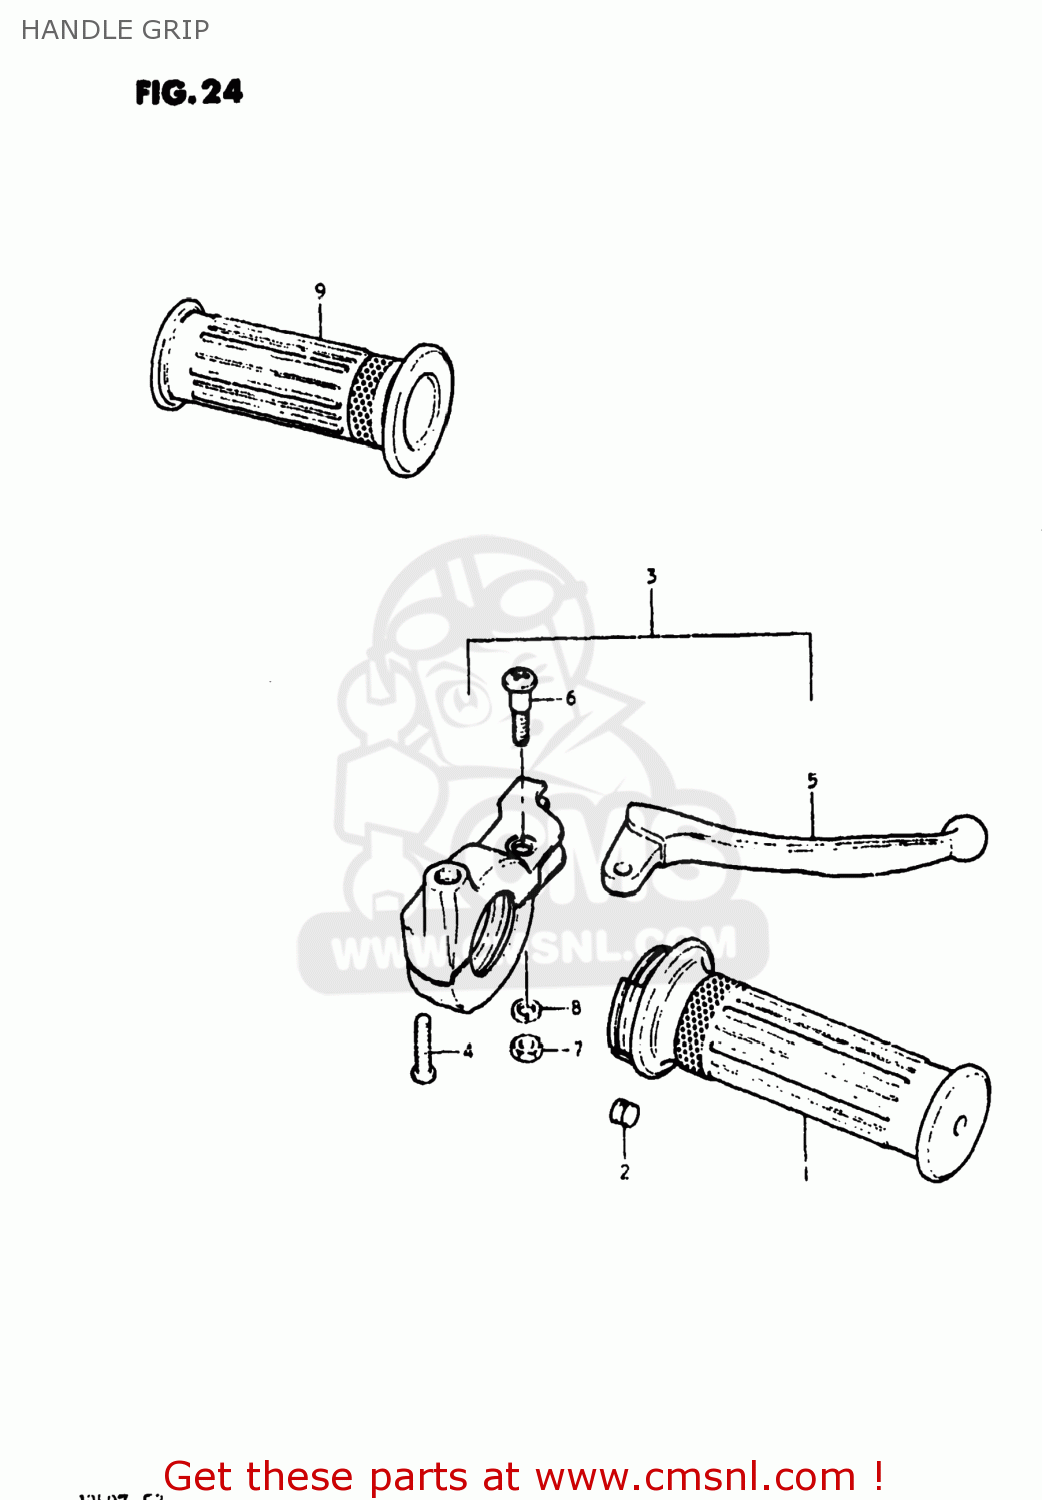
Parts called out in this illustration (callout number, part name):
1	GRIP,THROTTLE
2	PIECE,THROTTLE END
3	LEVER ASSY,BRAKE
4	SCREW
5	LEVER,BRAKE
6	SCREW
7	NUT
8	LOCK WASHER
9	GRIP,L
